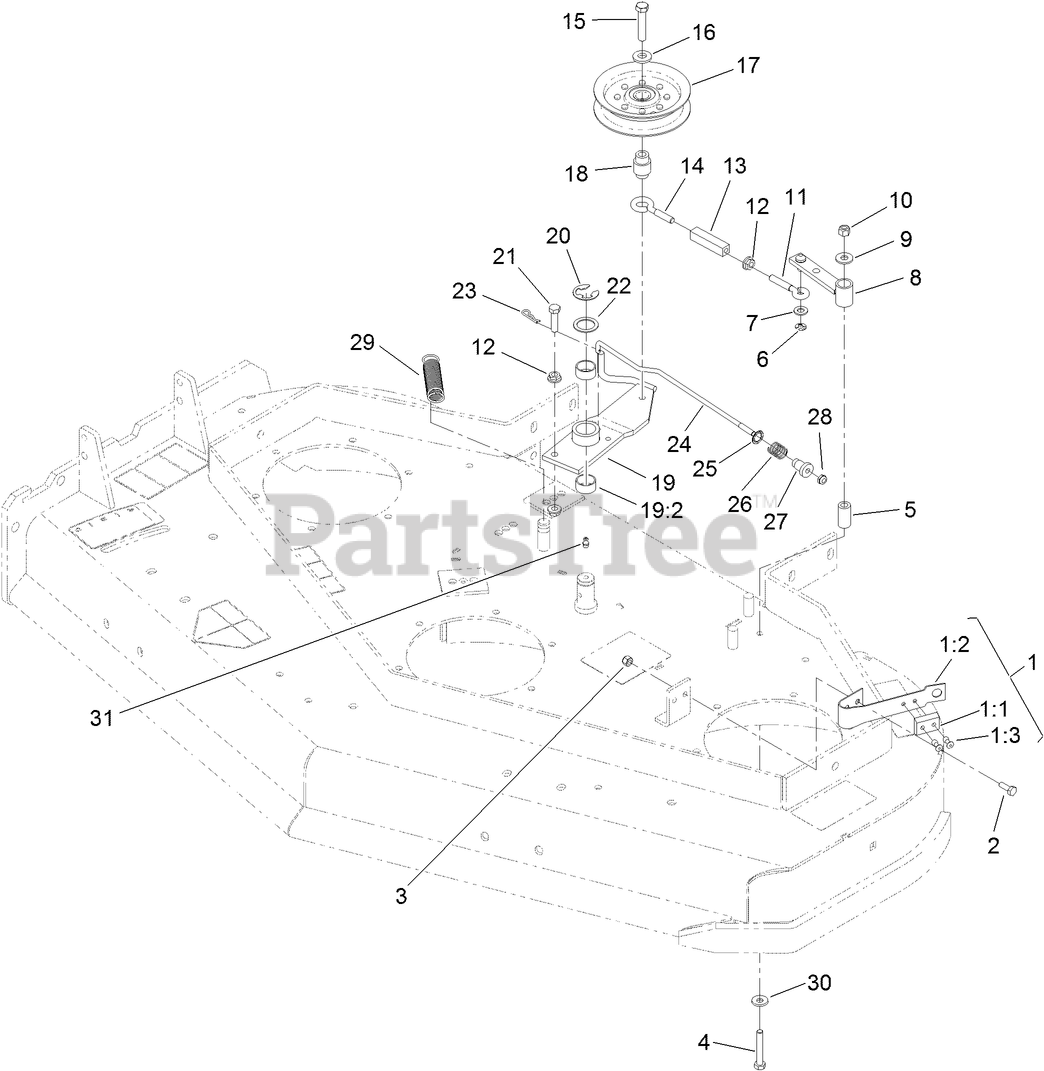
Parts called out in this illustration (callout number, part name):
1	PAD AND SPRING ASM
1:1	PAD-BRAKE
1:2	SPRING
1:3	RIVET-POP
2	SCREW-HH
3	NUT-LOCK, NI
4	SCREW-HH
5	TUBE-PIVOT
6	RING-RETAINING, EXT
7	WASHER-PLAIN
8	ARM-ASSIST, 32/36
9	WASHER-FLAT
10	NUT-LOCK, NI
11	EYEBOLT-THREAD, RH
12	NUT-HF
13	BODY-TURNBUCKLE
14	EYEBOLT-THREAD, LH
15	SCREW-HH
16	WASHER-BELLEVILLE
18	BUSHING-ENGAGEMENT
19	IDLER ARM ASM
19:2	SLEEVE-BEARING
20	RING-RETAINING, EXT
21	SCREW-HH, SPECIAL
22	WASHER-SPINDLE
23	PIN-COTTER
24	ROD-BRAKE
25	RING-PUSH ON
26	SPRING-COMPRESSION
27	SPACER-FLANGED
28	NUT-LOCK, NI
29	SPRING-EXTENSION
30	WASHER-SPRING
31	FITTING-GREASE, 90 DEG
